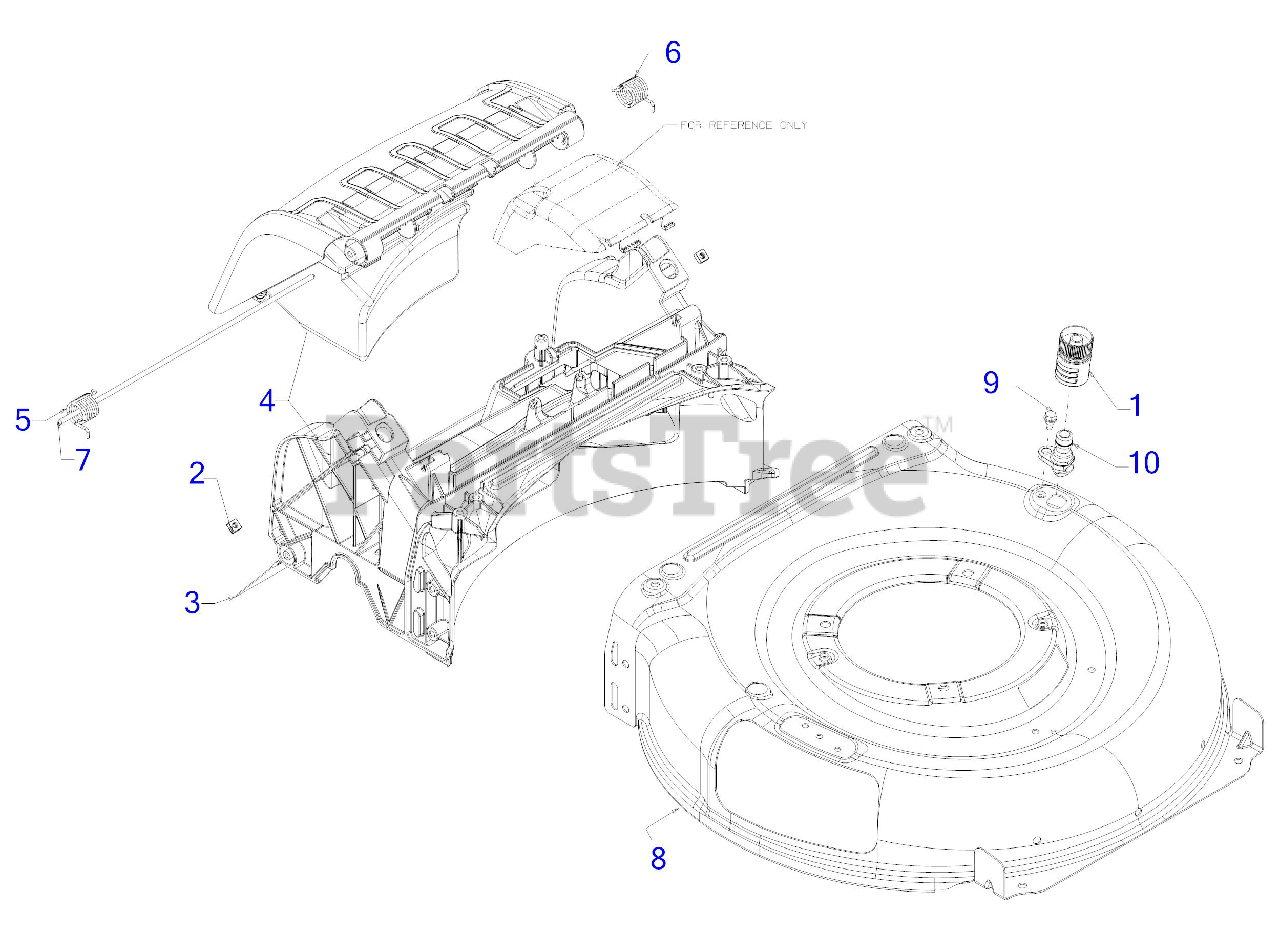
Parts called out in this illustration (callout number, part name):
1	WATER NOZZLE
2	SQUARE NUT 1/4-20
3	TRAILSHIELD
4	REAR BAG BAFFLE ASSEMBLY
5	TORSION SPRING (RH)
6	TORSION SPRING (LH)
7	REAR DOOR PIVOT ROD
9	SHOULDER SCREW 1/4-20 x .50
10	DECK WASH NOZZLE
